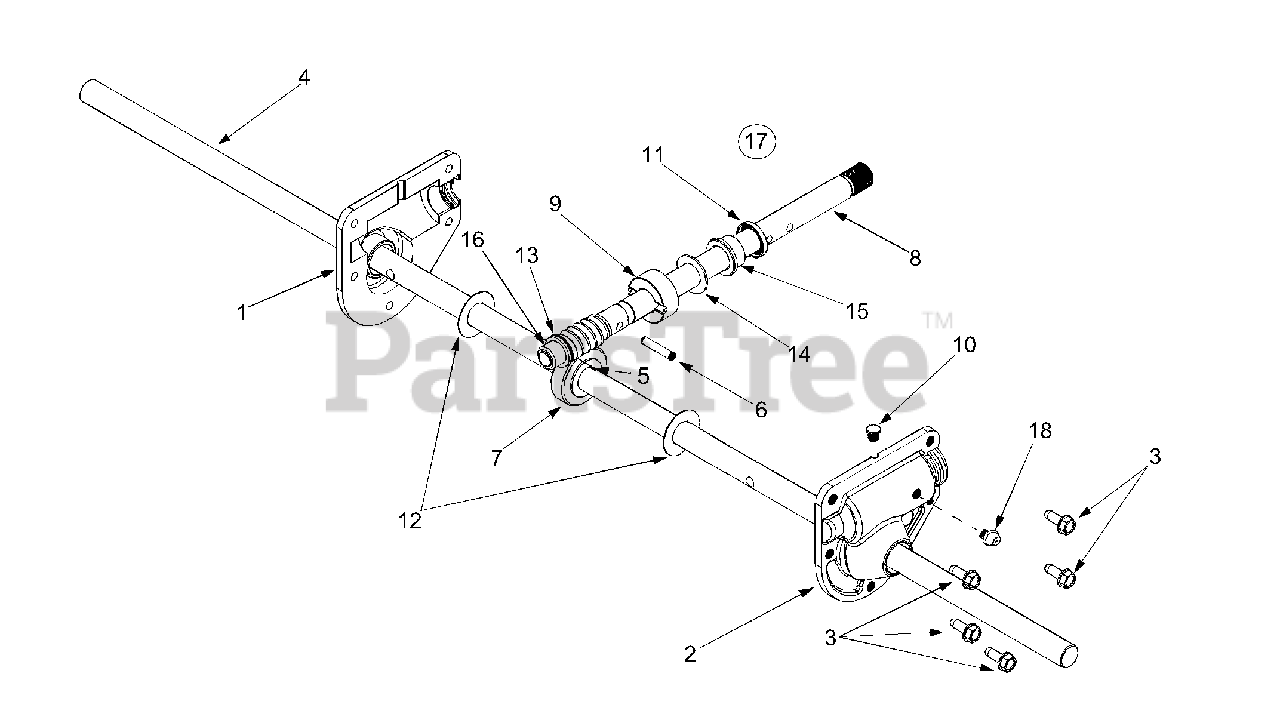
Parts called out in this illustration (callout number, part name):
1	RH Housing
2	LH Housing w/Fitting
3	Self Tapping Screw, 1/4-20 x .75
4	Spiral Axle 28"
5	Hi-Pro Key, 3/16 x 5/8
6	Spring Spiral Pin, .25 x 1.25
7	Worm Gear, 20-tooth
8	Worm Shaft
9	Thrust Collar
12	Flat Washer, .76 x 1.5 x .030
13	Flat Washer, .508 x 1.0 x .020
14	Flat Washer, .76 x 1.5 x .060
15	Flange Bearing, .75 x 1.0 x .59
16	Flange Bearing, .503 ID x .75 OD
17	Gear Assembly Complete, 28"
18	Grease Fitting, 3/16" Drive
